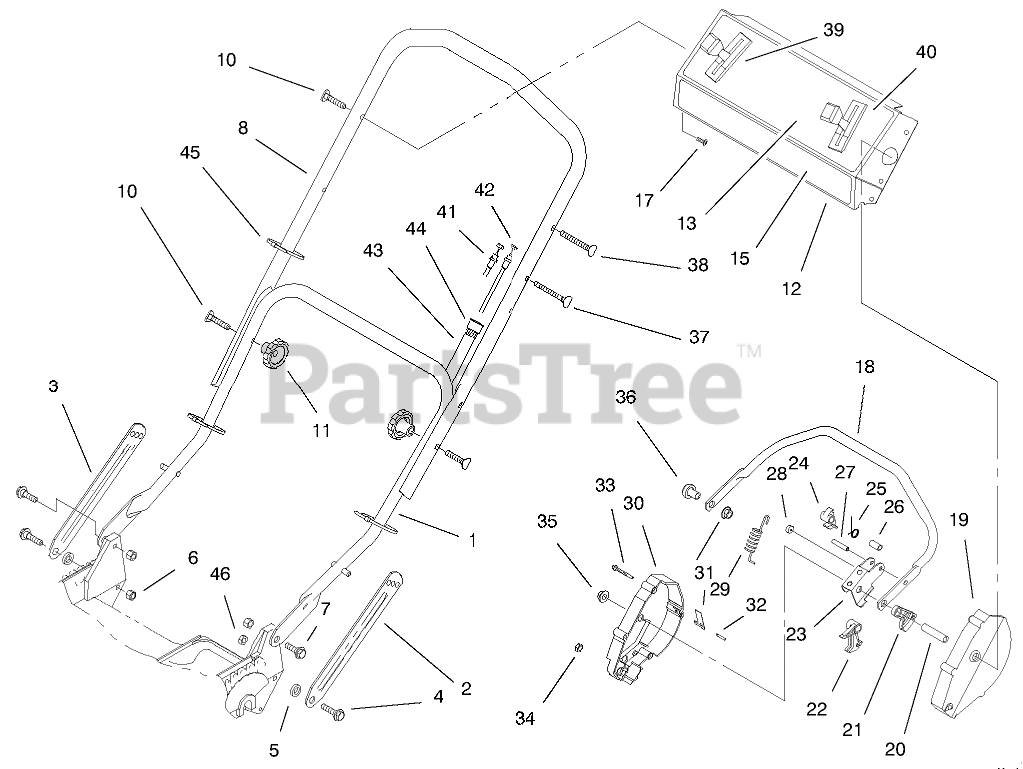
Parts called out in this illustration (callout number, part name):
1	ASM-Handle
2	Latch-Handle
3	Latch-Handle
4	SCREW-SHOULDER
5	SPACER
6	NUT-LOCK, NI
7	SCREW-SHOULDER
8	HANDLE - DIPPED
10	SCREW-HANDLE
12	Panel-Control (Incl. Ref. #13)
13	DECAL - INSRTUCTION
15	DECAL - CONSOLE
17	SCREW-TAP
18	Bar-Control
19	HOUSING-CONTROL, LH
20	TUBING-SPACER
21	LEVER-TRACTION
22	ROCKER
23	LEVER-CABLE
24	HOOK-CONTROL
25	SPRING-TORSION
26	SPACER
27	PIN-ROLL, SLOTTED
28	WASHER-NYLON
29	SPRING-DETENT
30	Housing-Control
31	SPRING-LEAF
32	PIN-INSERT
33	SCREW-HWHTF
34	NUT-LOCK NI
35	NUT-LOCK NI
36	SPACER-SUPPORT
37	SCREW-HANDLE
38	SCREW - HANDLE
39	CONTROL-SPEED, GROUND
40	THROTTLE CONTROL
41	CLUTCH CABLE
42	TRACTION CABLE
43	CONTROL CABLE COVER
44	FITTING-RING
45	TIE-CABLE
46	NUT-LOCK, NI
